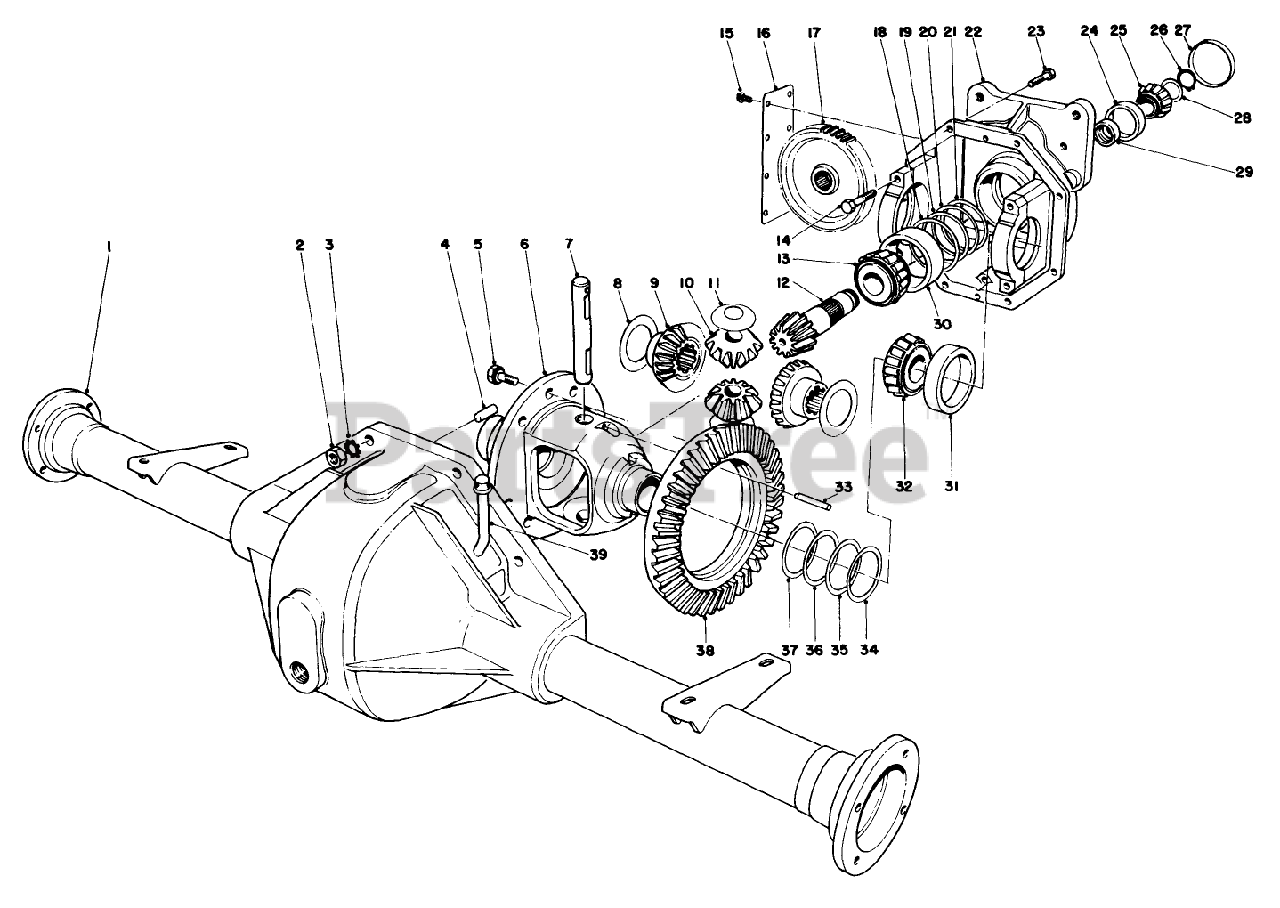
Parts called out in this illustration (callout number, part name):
1	HOUSING-LOWER
2	NUT-HEX
3	WASHER-LOCK
4	PIN-DOWEL
5	SCREW-GEAR, DRIVE
6	CASE-DIFFERENTIAL
7	SHAFT-MATE, PINION
8	WASHER-THRUST
9	GEAR-DIFFERENTIAL
10	PINION-DIFFERENTIAL
11	WASHER-THRUST, PINION
13	BEARING-ROLLER, CONE TAPER
14	SCREW-HH
15	SCREW
16	COVER-GEAR
17	Gear-Spur
18	Plunger
19	SHIM-PINION (.005)
20	SHIM-PINION (.010)
21	SHIM-PINION (.030)
22	Upper Housing (Incl. Ref. #14)
23	SCREW-HH
24	BEARING-CUP
25	CONE-BEARING
26	RING-SNAP
27	PLUG-CUP
28	SHIM-BEARING, FRONT
29	SPACER-BEARING
30	BEARING-TAPER, CUP
31	CUP-BEARING, ROLLER
32	BEARING-ROLLER, CONE
33	PIN-ROLL
34	SHIM-BEARING, DIFFERENTIAL (.003)
35	SHIM-BEARING, DIFFERENTIAL (.005)
36	SHIM-BEARING, DIFFERENTIAL (.010)
37	SHIM-BEARING, DIFFERENTIAL (.030)
38	Ring Gear
39	Vent Assembly
